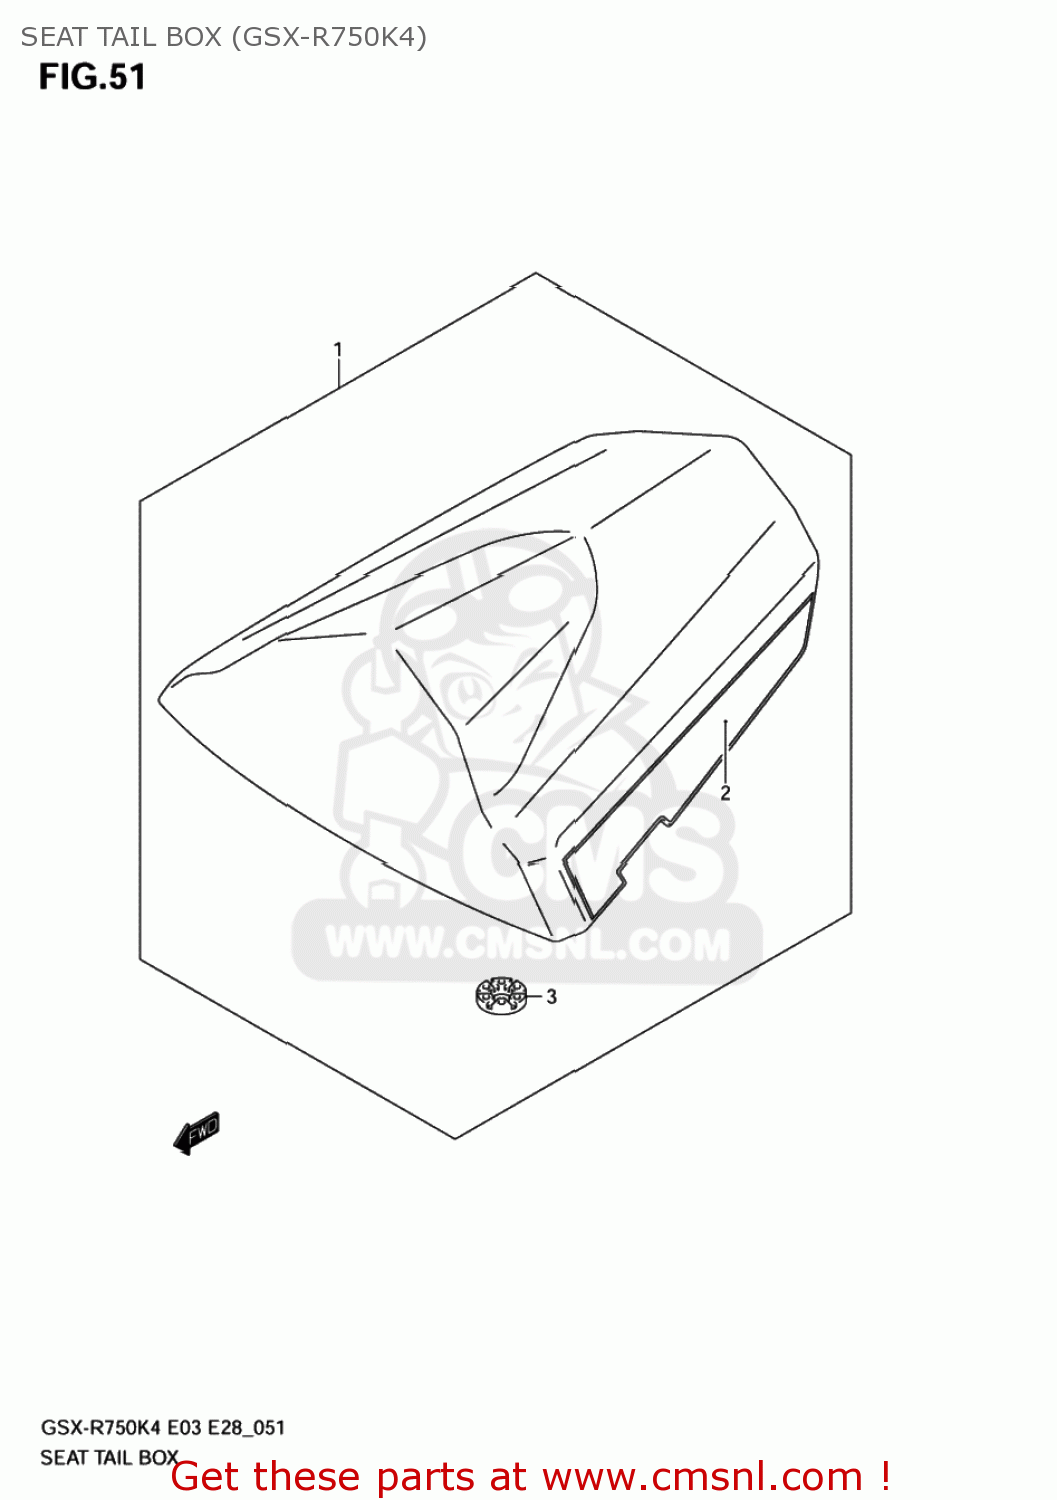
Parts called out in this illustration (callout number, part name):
1	BOX ASSY,SEAT TAIL(GRAY)
2	TAPE SET,BOX SEAT TAIL
3	CUSHION
